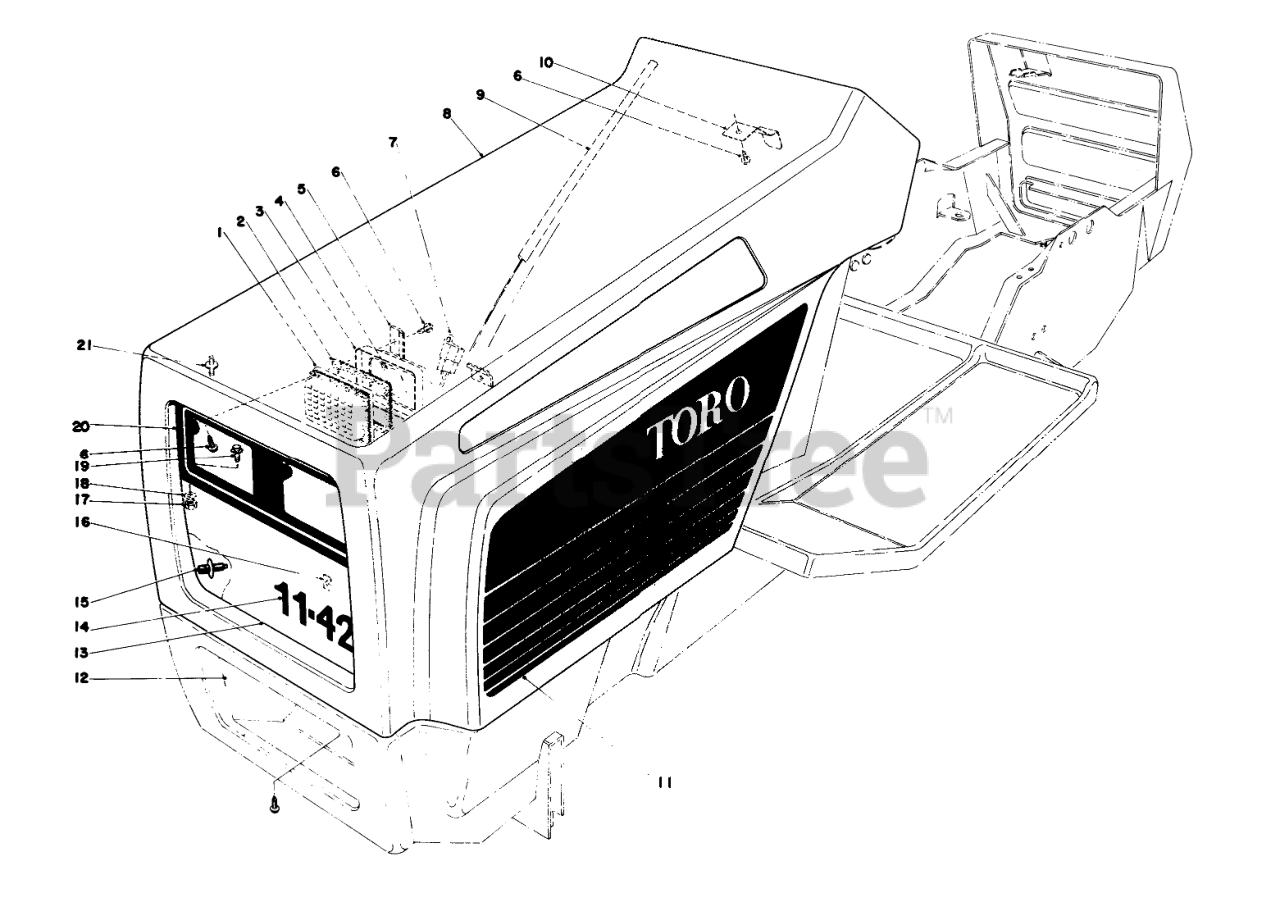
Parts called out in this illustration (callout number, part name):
1	Lens
2	Gasket Lens
3	Reflector
5	HEADLIGHT CLAMP
6	SCREW-HWHTF
7	CONNECTOR BODY
8	Hood (Incl. Ref. #15 & 21)
9	RUBBER EXT SEAL
10	SPRING LATCH
11	Decal Hood LH.
12	LOWER GRILLE
13	HEADLIGHT GRILLE
14	GRILLE NAMEPLATE
15	HINGE BRKT STUD
17	NUT-LOCK, SIDE
18	WASHER-FLAT
19	SCREW-SHWH
20	HEADLIGHT PANEL B
21	Stud Hood Duct
